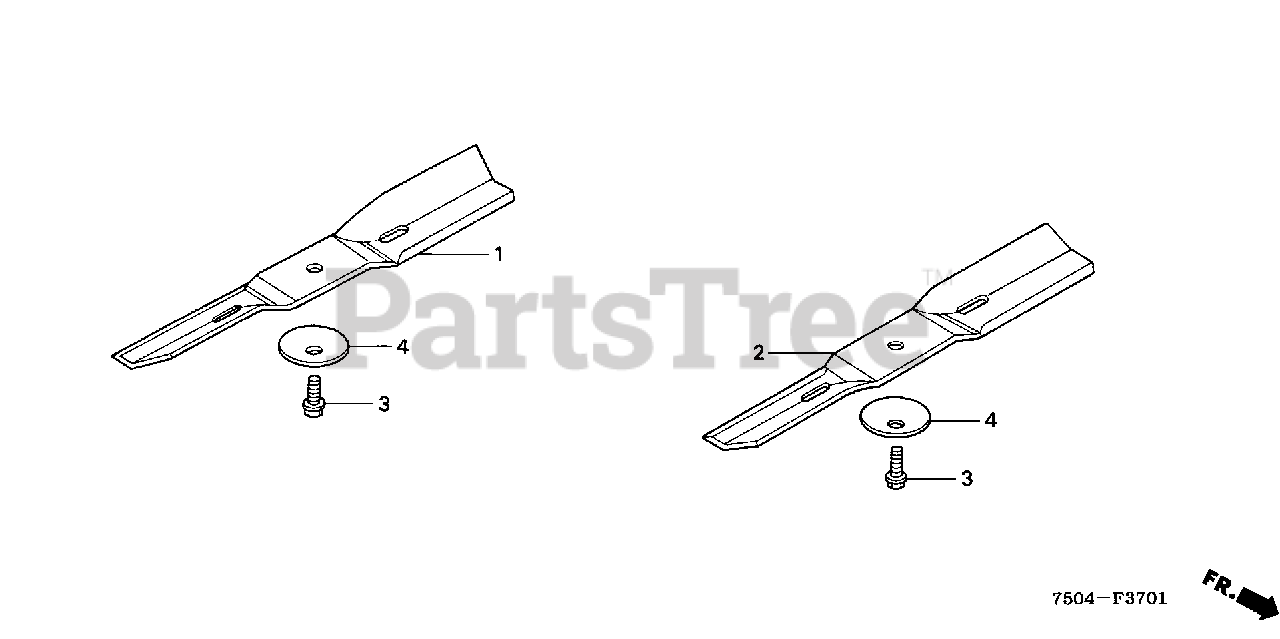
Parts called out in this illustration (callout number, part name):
1	BLADE, R. ROTARY
2	BLADE, L. ROTARY
3	BOLT, BLADE HOLDER
3	BOLT, BLADE HOLDER (10X28)
4	WASHER, BLADE
